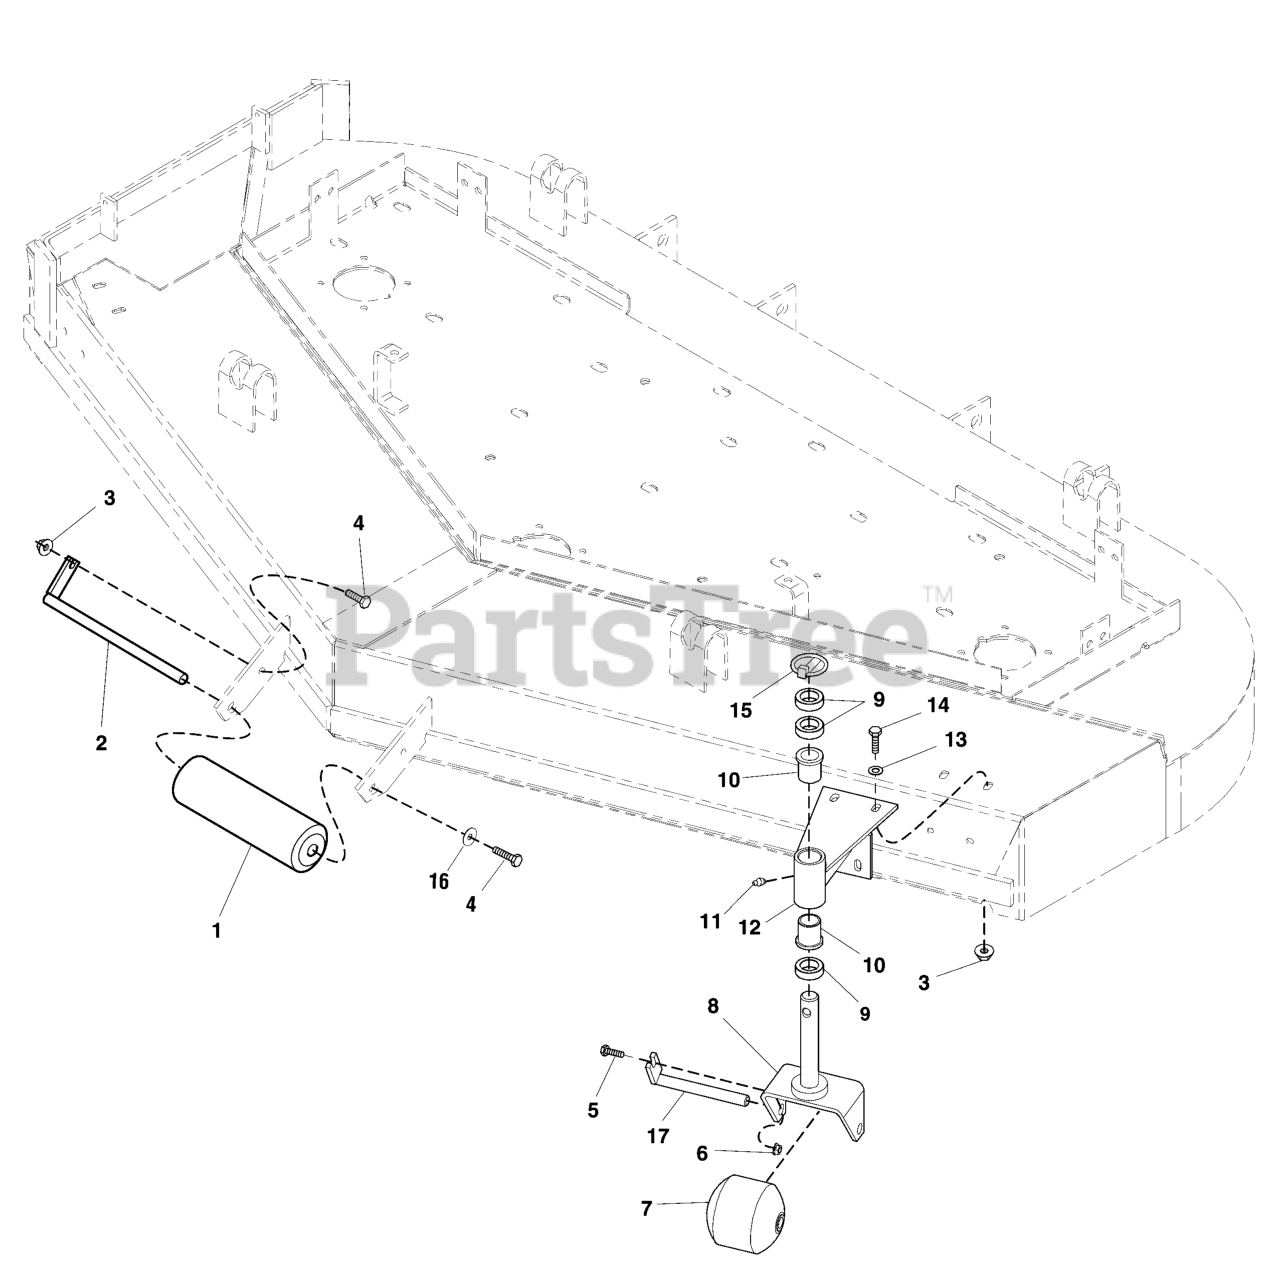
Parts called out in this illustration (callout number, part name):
1	ROLLER
3	NUT, 3/8-16 Hex Serrated Flange
4	BOLT, 3/8-16 X 1" GD5 CZ
5	BOLT, 5/16-18 X 3/4 GD5
6	NUT, 5/16-18 HEX SERRATED FLANGE (SMALL)
7	ROLLER, Caster
8	CASTER YOKE
9	SPACER, 1.02 x 1.56 x .50
10	BUSHING, FLANGE
11	GREASE FITTING
12	CASTER MOUNT ARM
13	WASHER, 3/8 SAE
14	BOLT, 3/8-16 X 3/4" GD5 CZ
15	PIN, Lynch
16	WASHER, .390 X 1.50 X .109 YZ
17	CASTER ROLLER PIN
